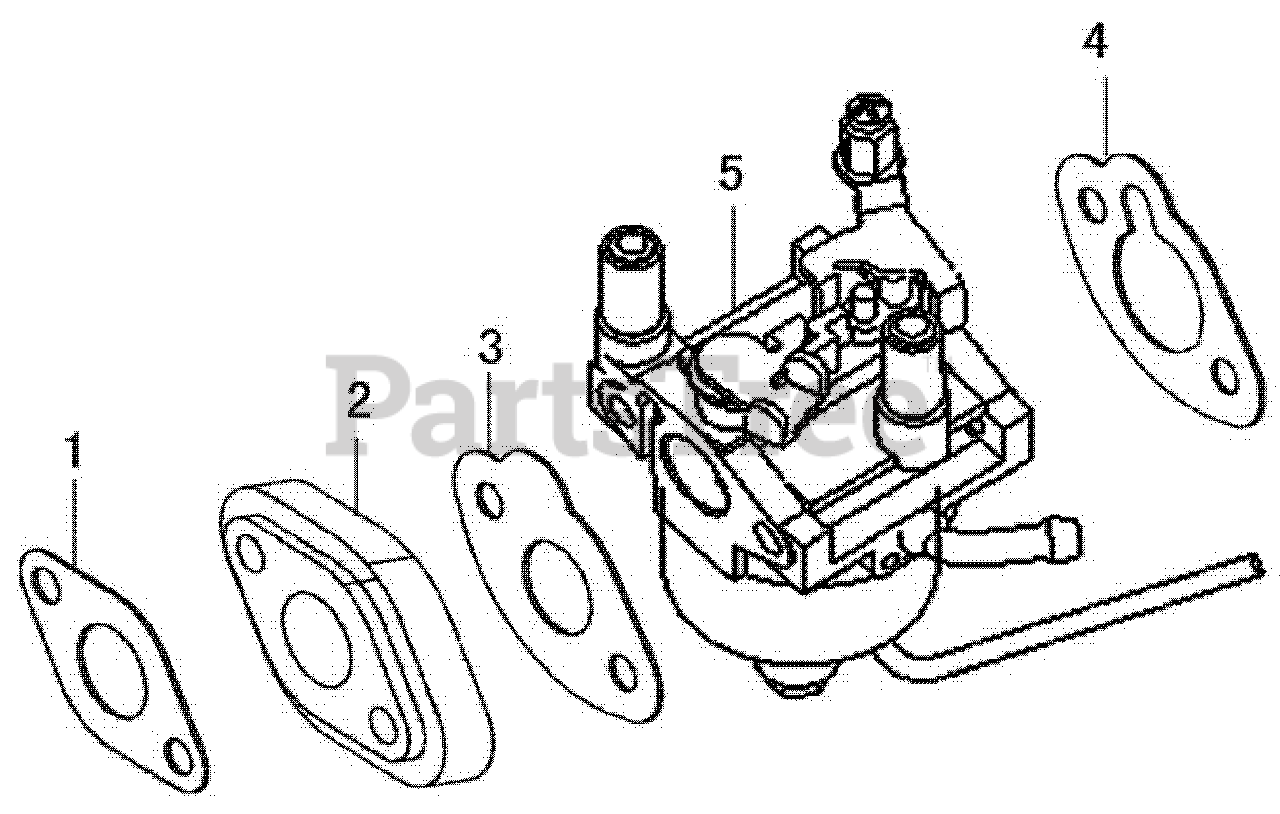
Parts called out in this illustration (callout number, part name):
1	GASKET, INSULATOR
2	INSULATOR , CARBURETOR
3	PACKING, CARBURETOR
4	PACKING, CARBURETOR
5	CARBURETOR
